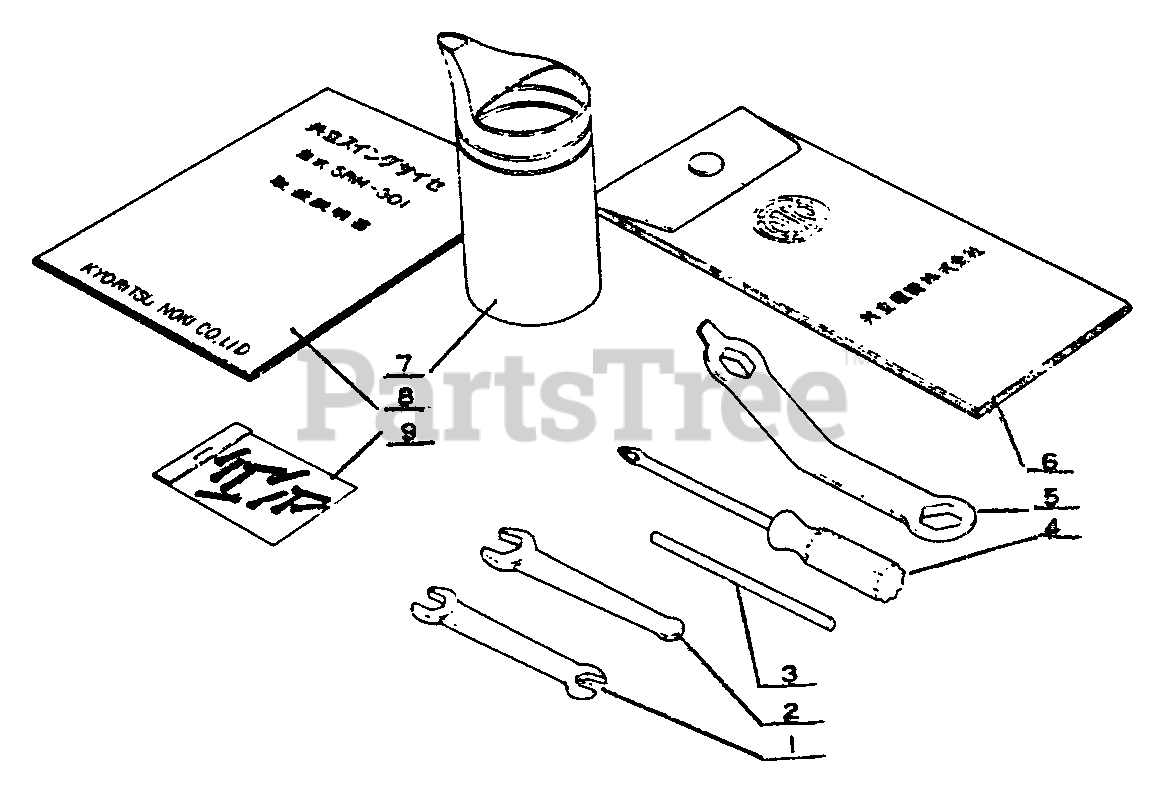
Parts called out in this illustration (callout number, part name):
1	SPANNER - 8X10mm
2	SPANNER - 13mm
3	FITTING TOOL
4	SCREWDRIVER - (+)
5	SPANNER - 17X18mm
6	BAG, TOOL
7	Fuel mixer
8	OWNER'S MANUAL
10	PIN, SPLIT - 2X22
